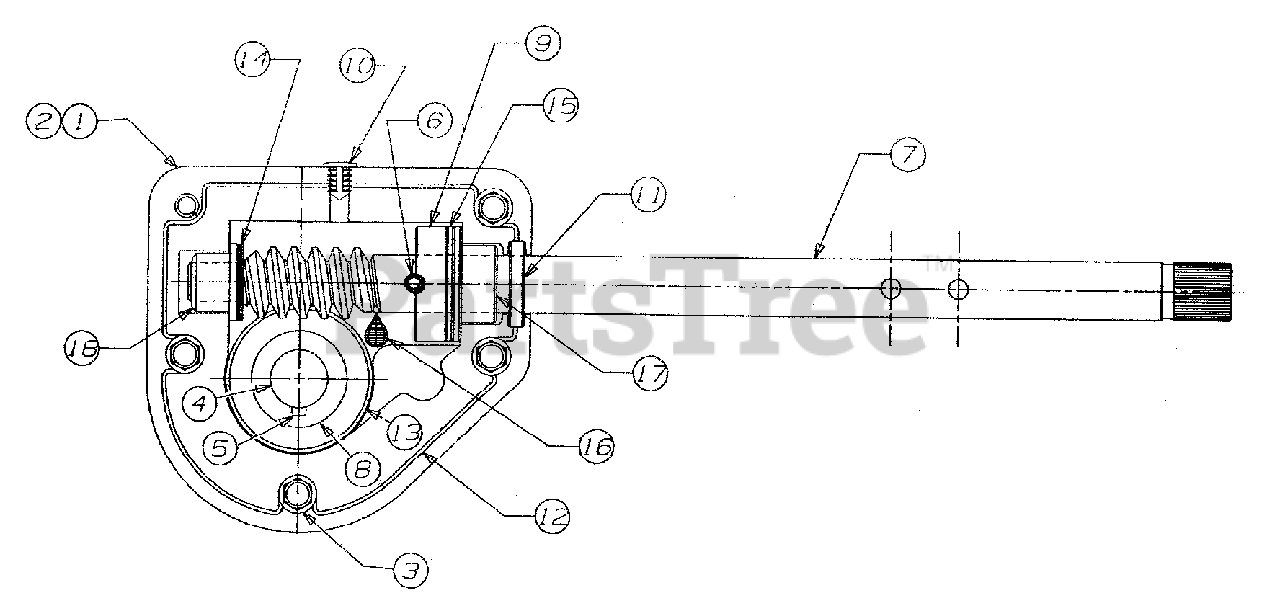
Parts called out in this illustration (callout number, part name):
1	Housing-L.H.
2	Housing-R.H.
3	Screw
4	Spiral Axle 24"
5	Key
6	Pin-Spiral
7	Shaft-Worm
8	Gear-Worm
9	Collar-Thrust
11	Seal-Oil
12	Locktite 5699
13	Washer-Flat
14	Washer-Flat
15	Washer-Flat
16	Grease
17	Bearing-Flange
18	Bearing-Flange
